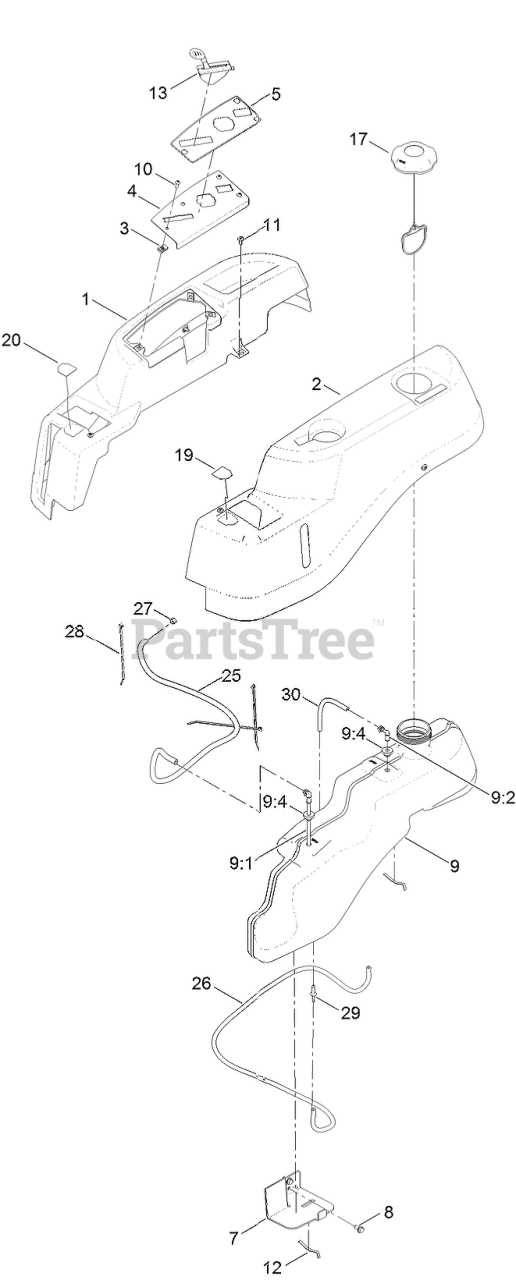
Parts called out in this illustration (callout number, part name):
1	POD-RH
2	POD-LH
4	PLATE-CONTROL
5	DECAL-PANEL, CONTROL
7	SUPPORT-TANK, FRONT
8	SCREW-HWHTF
9	FUEL TANK ASM
9:1	CONNECTOR-ELBOW, 90 DEG
9:2	BUSHING
9:4	FITTING-PLASTIC
10	SCREW-PRH
11	SCREW-SHOULDER
12	SPRING
13	CABLE-THROTTLE (45.0 IN)
17	CAP-FUEL, RATCHETING
19	DECAL-CONTROL LEVER, LH
20	DECAL-CONTROL LEVER, RH
25	HOSE-FUEL
26	HOSE-FUEL
27	CLAMP-HOSE
28	TIE-CABLE
29	ADAPTOR-ORIFICE
30	HOSE-FUEL
